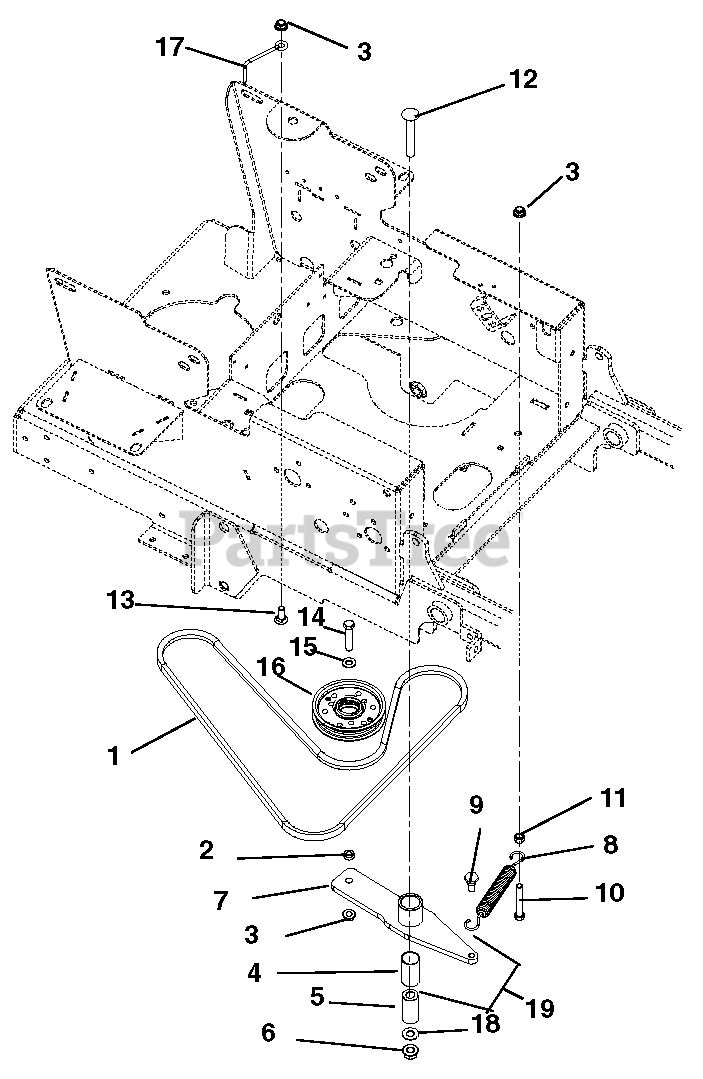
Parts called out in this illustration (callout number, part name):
1	Belt, 4L 67.47 Wrapped
2	Bushing, Sleeve .377 x .624 x .235
3	Nut, .38-16 Nyloc Flange
4	Bushing, 1.00 x 1.125 x 1.936
5	Bushing, Spacer .502 x .997 x 2.03
6	Nut .50-13 Nyloc Flange
7	Weldment, Hydro Drive Idler Arm
8	Spring, Extension
9	Bolt, Shoulder EP .38-16 x .30 Hex
10	Bolt, Hex .38-16 x 2.50 Grade 5
11	Nut, Locking-Center .375-16
12	Bolt, Hex .50-13 x 3.25 Grade 5
13	Bolt, Round Head Square Neck .38-16 x 1.00 Grade 5
14	Bolt, Hex .38-16 x 2.00 Grade 5
15	Washer, Flat-Steel .406 x .812 x .065
16	Assembly, 4" Idler
17	Belt Finger
18	Washer, Flat-STL.511 x 1.441 x .125
19	Assembly, Idler Pivot Arm (Includes item 4 and 7)
